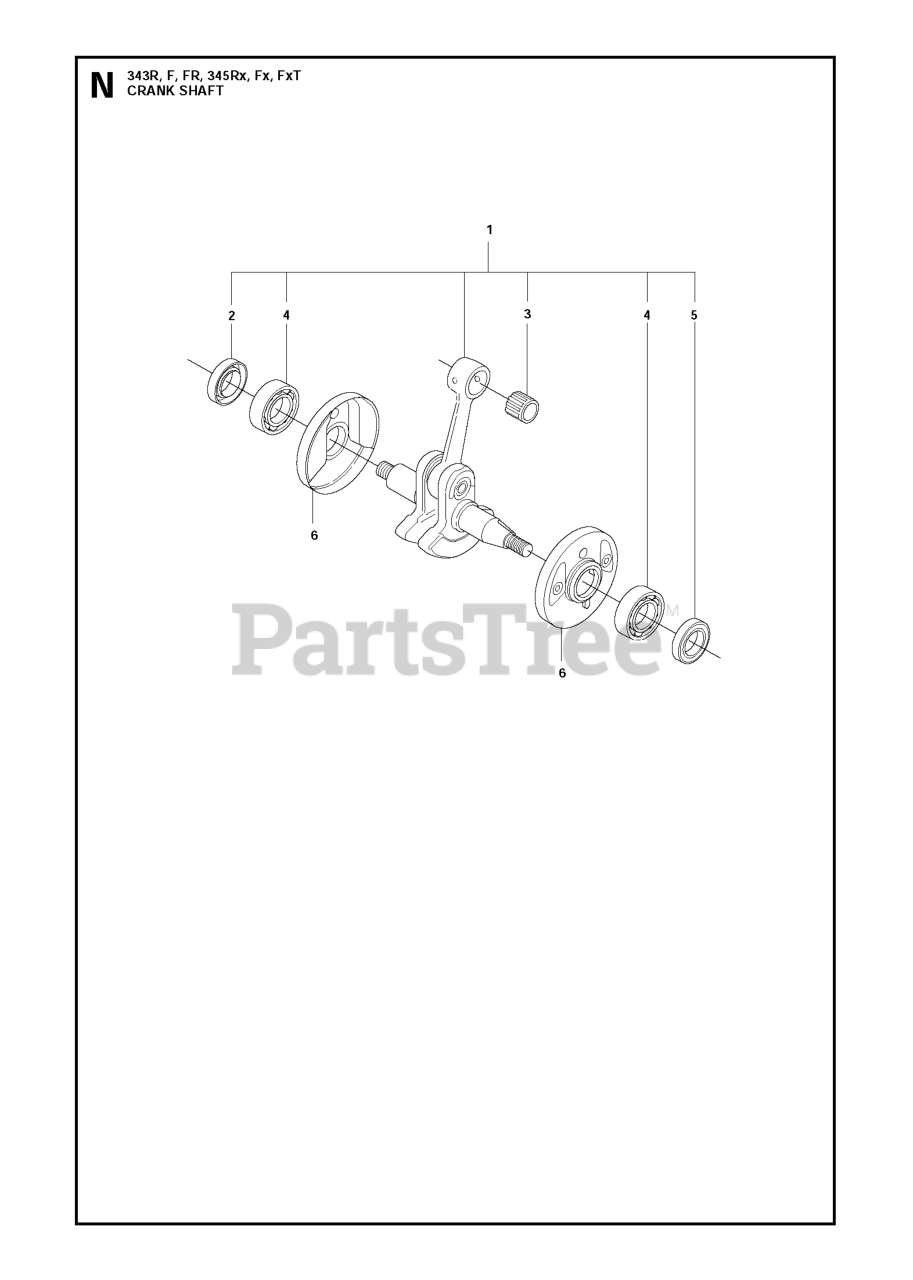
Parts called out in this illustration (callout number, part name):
1	CRANKSHAFT
2	SEALING RING
3	SUPPORT BUSHING
4	BALL BEARING
6	COLLAR
